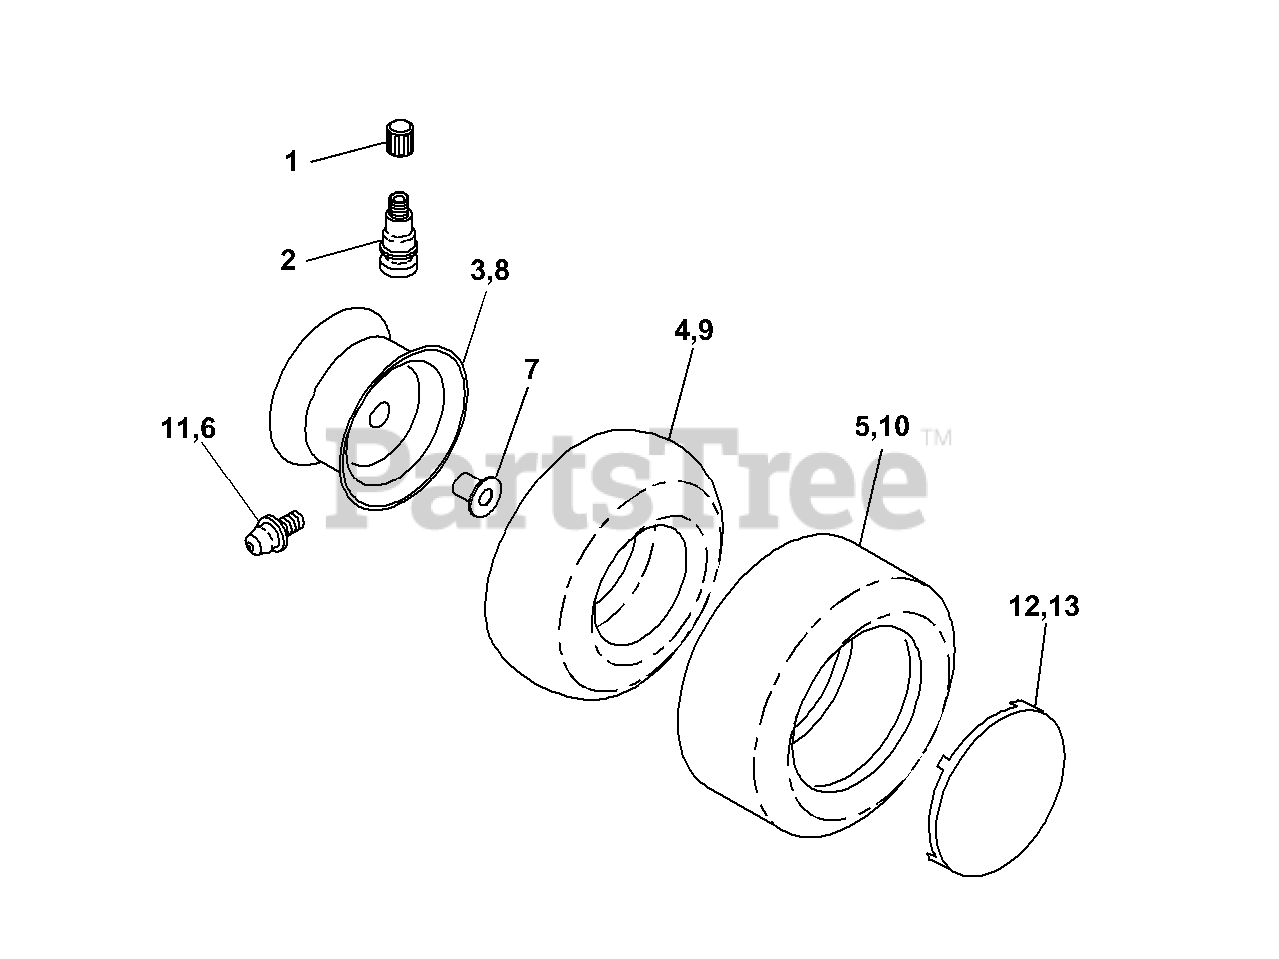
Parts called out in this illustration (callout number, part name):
2	VALVE STEM LT
3	RIM ASSY-FRONT
4	TUBE.16X6.5/7.5-8
5	TIRE HEAVY DUTY
6	FITTING LT
7	BEARING T
8	RIM.ASM.12X7.REAR.WHITE
9	TUBE.23X9.5-12
10	TIRE HEAVY DUTY
11	ZERK FITTING M
12	CAP,HUB REAR
13	COVER,WHEEL
